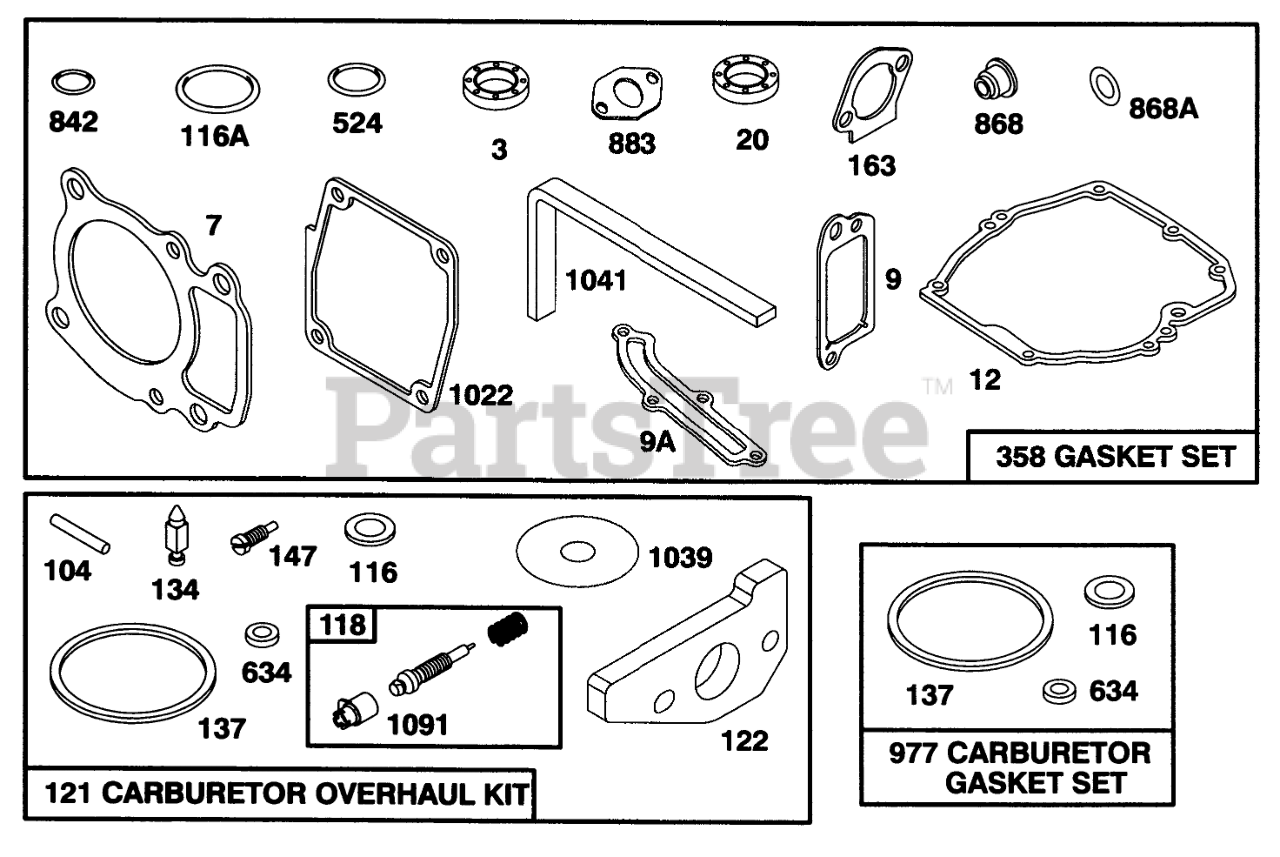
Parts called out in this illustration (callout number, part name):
3	SEAL - OIL
7	CYLINDER HEAD GASKET
9	BREATHER GASKET
9A	GASKET-BREATHER
12	ENGINE BASE GASKET
20	SEAL-OIL
104	FLOAT HINGE PIN
116	SEALING GASKET
116A	O RING SEAL
118	VALVE/SPRING - NEEDLE
121	KIT-CARBURETOR OVERHAUL
122	ADAPTER ASSEMBLY
134	Valve-Inlet (Includes Seat)
137	FLOAT BOWL GASKET
147	JET - PILOT
163	AIR CLEANER GASKET
358	GASKET SET
524	O-RING
634	SEAL WASHER
842	O-RING
868	SealAssy-Valve
868A	Seal-Valve
883	EXHAUST GASKET
977	CARBURATOR GASKET SET
1022	ROCKER COVER GASKET
1039	FLOAT LIMITER
1041	SEAL - FOAM
1091	CAP - LIMITER
